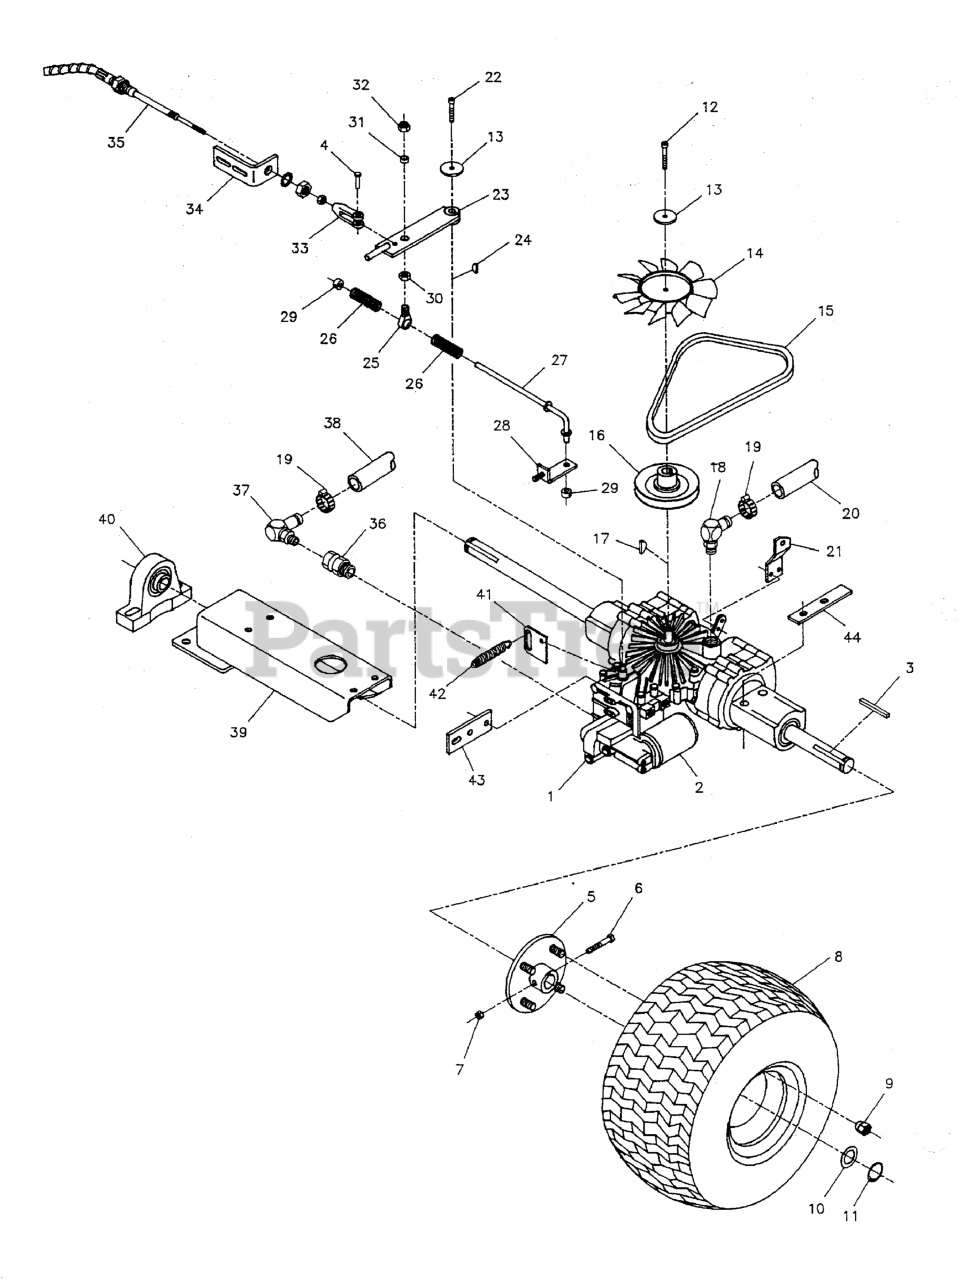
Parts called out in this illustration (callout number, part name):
1	Transmission
2	FILTER, Transmission Oil
3	Drive Axle Key
4	CLEVIS PIN, 1/4 x 1
5	DRIVE HUB DETAIL
6	BOLT, 5/16-24 x 2" GD 8
7	NUT, 5/16-24 HEX NYLON LOCK
8	WHEEL & TIRE ASSEMBLY, 20 x 10 x 8, Complete
8	TIRE & WHEEL ASSEMBLY, 18 X 8.5 X 8
9	LUG NUT, 1/2-20
11	RING, Retaining
12	BOLT, Allen Head, 1/4-20 x 1-3/4
13	WASHER, .265 x 1.50 x .109
15	BELT, A-Section
16	PULLEY, Transmission Input
17	KEY, Hi-Pro Woodruff
18	FITTING, 90 Degrees 7/8" O-Ring
19	CLAMP, #10 Hose
20	Transmission Inlet Hose, 4.875" Long
21	BRAKE LEVER
22	BOLT, Allen Head, 1/4-20 x 1-1/2
23	TRANSMISSION CONTROL ARM
24	KEY, #3 Woodruff
25	BALL JOINT, 3/8-24 Male
26	SPRING, Compression
27	ROD, NEUTRAL SPRING WELDMENT
28	Spring Anchor
29	COLLAR, 5/16" Set
30	NUT, 3/8-24 Hex
31	SPACER, .38 x .50 x .27
32	NUT, 3/8-24 Hex Nylon Lock
33	5/16" Rod End Clevis
34	CABLE BRACKET
35	CABLE, Speed Control
36	FITTING, 7/8" O-Ring Straight Swivel
37	FITTING, 90 Degrees 1/2" NPT
38	HOSE, Transmission Return, 14.75"
39	AXLE SUPPORT
40	BEARING, PILLOW BLOCK, 1
41	DUMP VALVE LEVER
42	SPRING, Extension
43	BRACKET, Transmission Support
44	Differential Spacer
